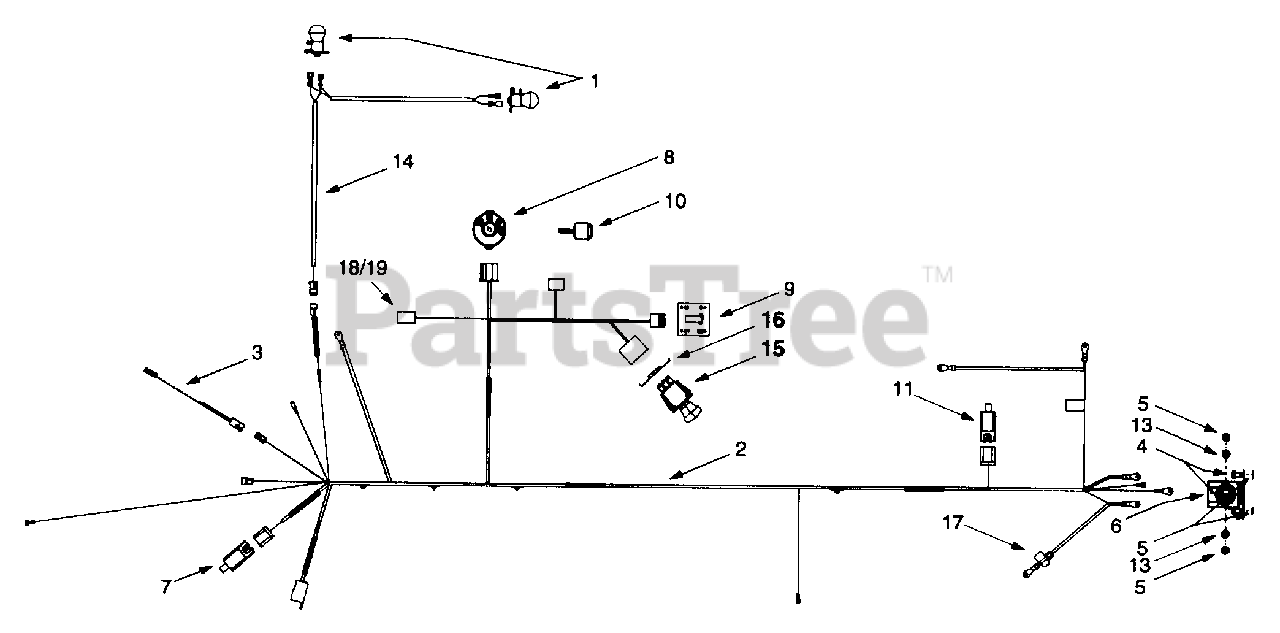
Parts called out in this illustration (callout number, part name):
1	Bulb/Socket Headlight Assembly
2	Wiring Harness
3	Harness Adapter, #18 x 5
4	Self Tapping Screw, 1/4-20 x .5
5	Hex Nut, 1/4-20
6	Solenoid, 12-volt, 100 Amp
7	Snap Mount Safety Interlock Switch (Brake)
8	Ignition Switch
9	Indicator Monitor / Hour Meter
10	Ignition Key
11	Safety Plunger Switch (Seat)
13	Lock Washer, 1/4
14	Headlight Harness
15	Electric PTO Switch
16	Retainer Bracket
17	Positive Terminal Cover (Boot)
18	Fuse Holder
19	20-amp Fuse
